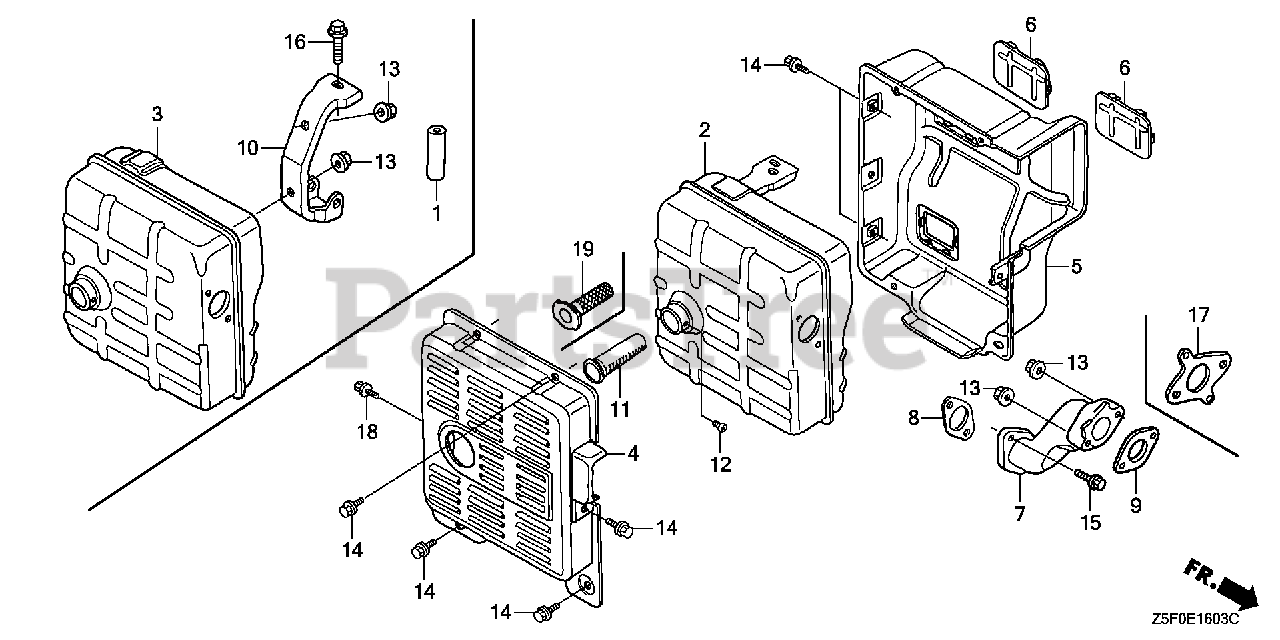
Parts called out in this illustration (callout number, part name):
3	MUFFLER (TSURUMI)
5	PROTECTOR, MUFFLER (INNER)
6	SEAL, MUFFLER PROTECTOR
8	GASKET, EX. PIPE
9	GASKET, EX. PIPE
11	ARRESTER, SPARK
12	SCREW, TAPPING (4X8)
13	NUT, FLANGE (8MM)
14	BOLT, FLANGE (6X10)
15	BOLT, FLANGE (8X20)
17	GASKET, EX. PIPE
18	BOLT, FLANGE (6X10)
